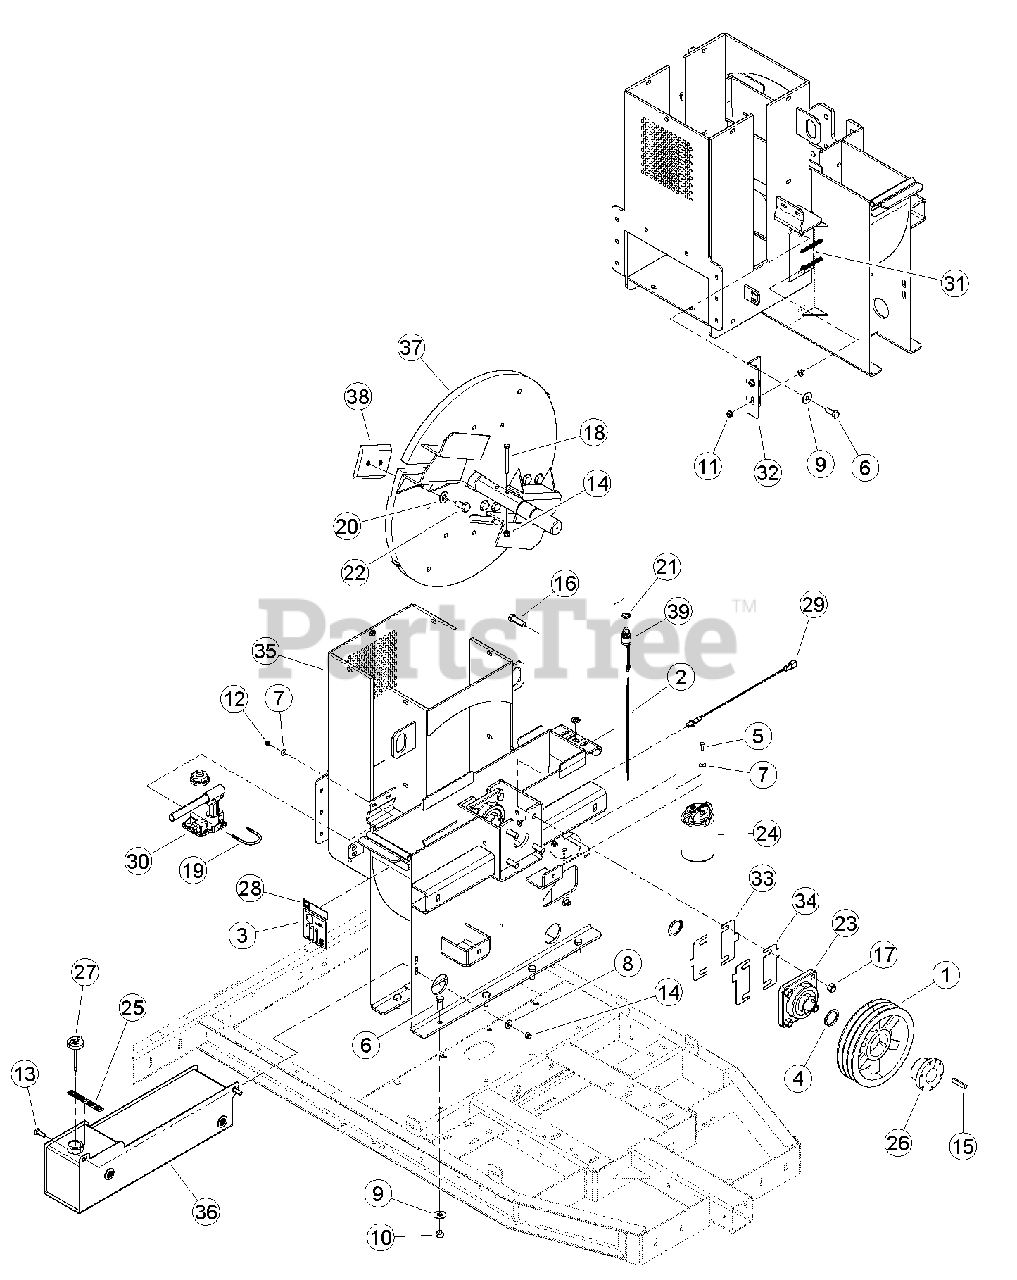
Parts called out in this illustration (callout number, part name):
1	SHEAVE, 3BQ9.4, SK
2	WIRE ASSY, ENGINE KILL
3	DECAL, 111 DB (CE COMPLIANT ONLY)
4	RING, 1-3/4 EXT HEAVY DUTY SNAP
5	BOLT, 1/4 X 3/4 HEX HD GR5 ZP
6	BOLT, 1/2 X 1-1/4 HEX HD GR5 NC ZP
7	WASHER, 1/4 FLAT ZP
8	WASHER, 3/8 FLAT ZP
9	WASHER, 1/2 FLAT ZP
10	NUT, 1/2 CENTERLOCK GRB ZP
11	NUT, 3/8 SERR FLANGE NC ZP
12	NUT, 1/4 NE NYLOCK ZP
13	BOLT, 3/8 X 1-1/4 CRG GR5 NC ZP
14	NUT, 3/8 NE NYLOCK ZP
15	KEY, 3/8 SQUARE X 2 LONG PLAIN
16	BOLT, 9/16 X 1-3/4 HEX HD GR5 ZP
17	NUT, 9/16 CENTER LOCK GRB ZP
18	BOLT, 3/8 X 3-1/2 FULL THD GR5 ZP
19	U-BOLT, 1/4 X 1-1/2 PIPE
20	WASHER, 5/8 SAE HARDENED
21	NUT, 5/8-32 JAM
22	BOLT, M16 X 2.0 X 30 HEX HD W/ PATCH
23	BEARING, 1-3/4" 4 BOLT FLANGE
24	FILTER, SPIN-ON
25	DECAL, HYDRAULIC FLUID
26	BUSHING, SK 1-3/4"
27	CAP, W/DIPSTICK
28	DECAL, 76628S INFORMATION (CE COMPLIANT ONLY)
29	SENSOR, M12 PNP PROXIMITY
30	JACK, HYDRAULIC 2 TON
31	PLATE, CHIPPER ANVIL
32	WELDMENT, BLOCK ADJUSTOR
33	SHIM, 20 GA.
34	SHIM, 16 GA.
35	WELDMENT, 6 IN CHIPPER HOUSING
36	WELDMENT, HYDRAULIC TANK
37	WELDMENT, 6 CHIPPER DISK
38	KIT, CHIPPER BLADE
39	ASSEMBLY, SEALED SWITCH
